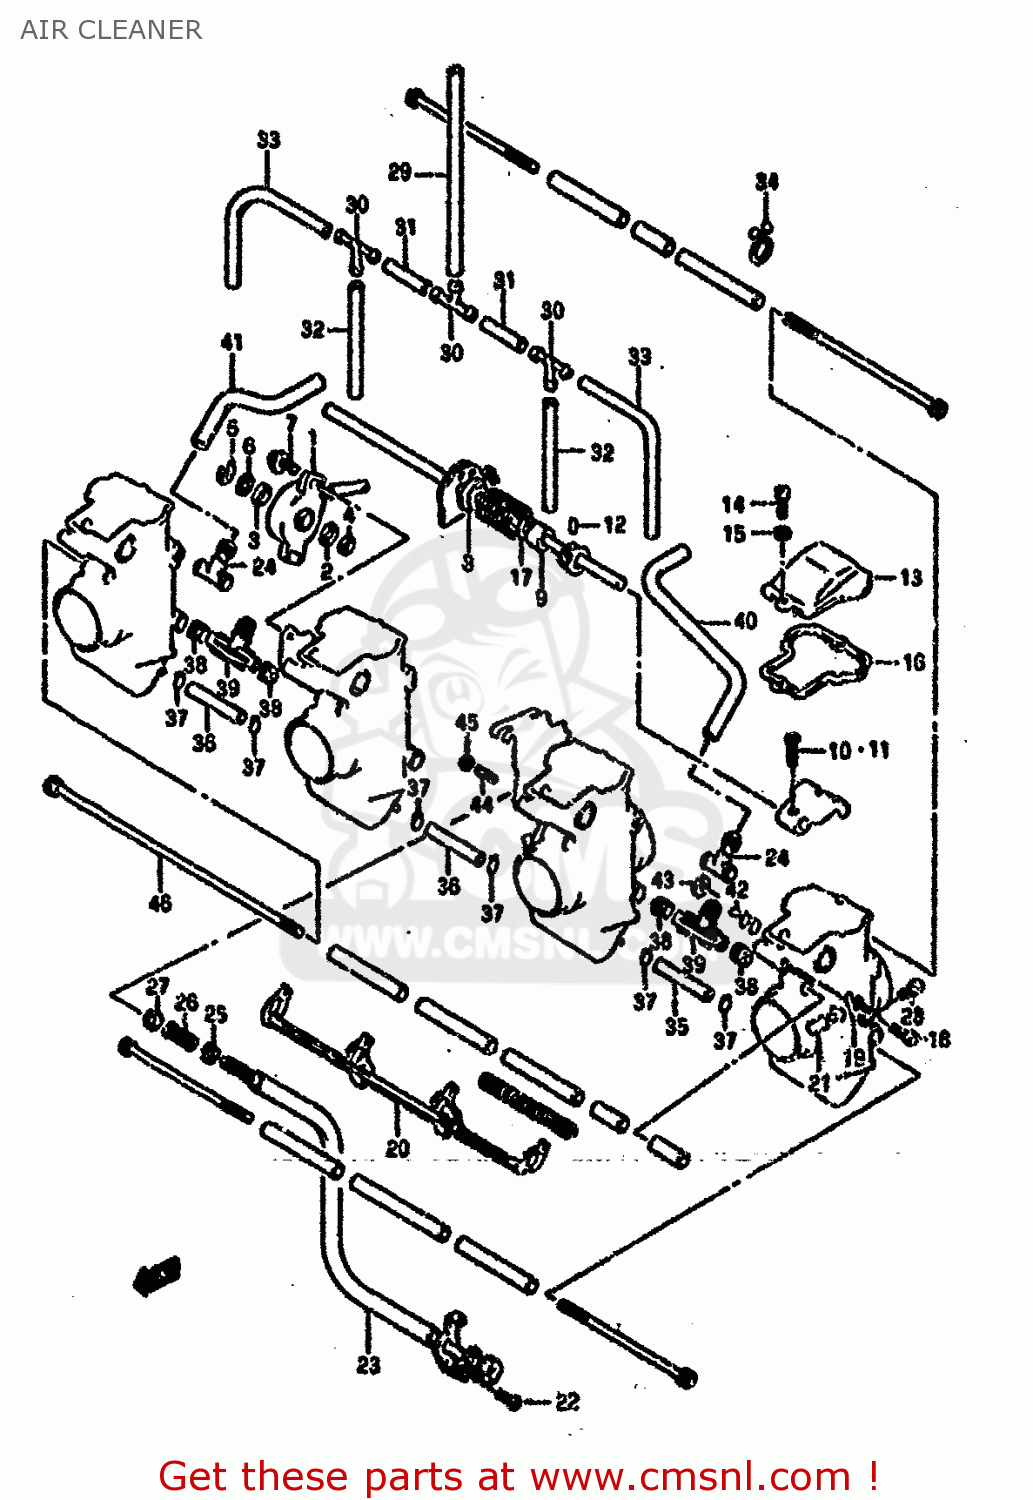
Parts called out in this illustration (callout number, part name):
1	CLEANER ASSY,AIR
2	FILTER,AIR
3	CAP,AIR CLEANER
4	SCREW
5	TUBE,INLET
6	TUBE,OUTLET
7	CLAMP
8	TUBE,BREATHER
9	CLIP
10	TUBE,DRAIN
11	CLIP
12	STOPPER,DRAIN
13	CLIP
14	BRACKET COMP,AIR CLEANER
15	BRACKET COMP,AIR CLEANER
16	SCREW 6X12
17	SCREW
18	VALVE ASSY,MAIN AIR SOLENOID
19	NUT
20	HOSE(4X7X600)
21	BRACKET,SOLENOID VALVE
22	FILTER,SOLENOID VALVE
23	UNION
